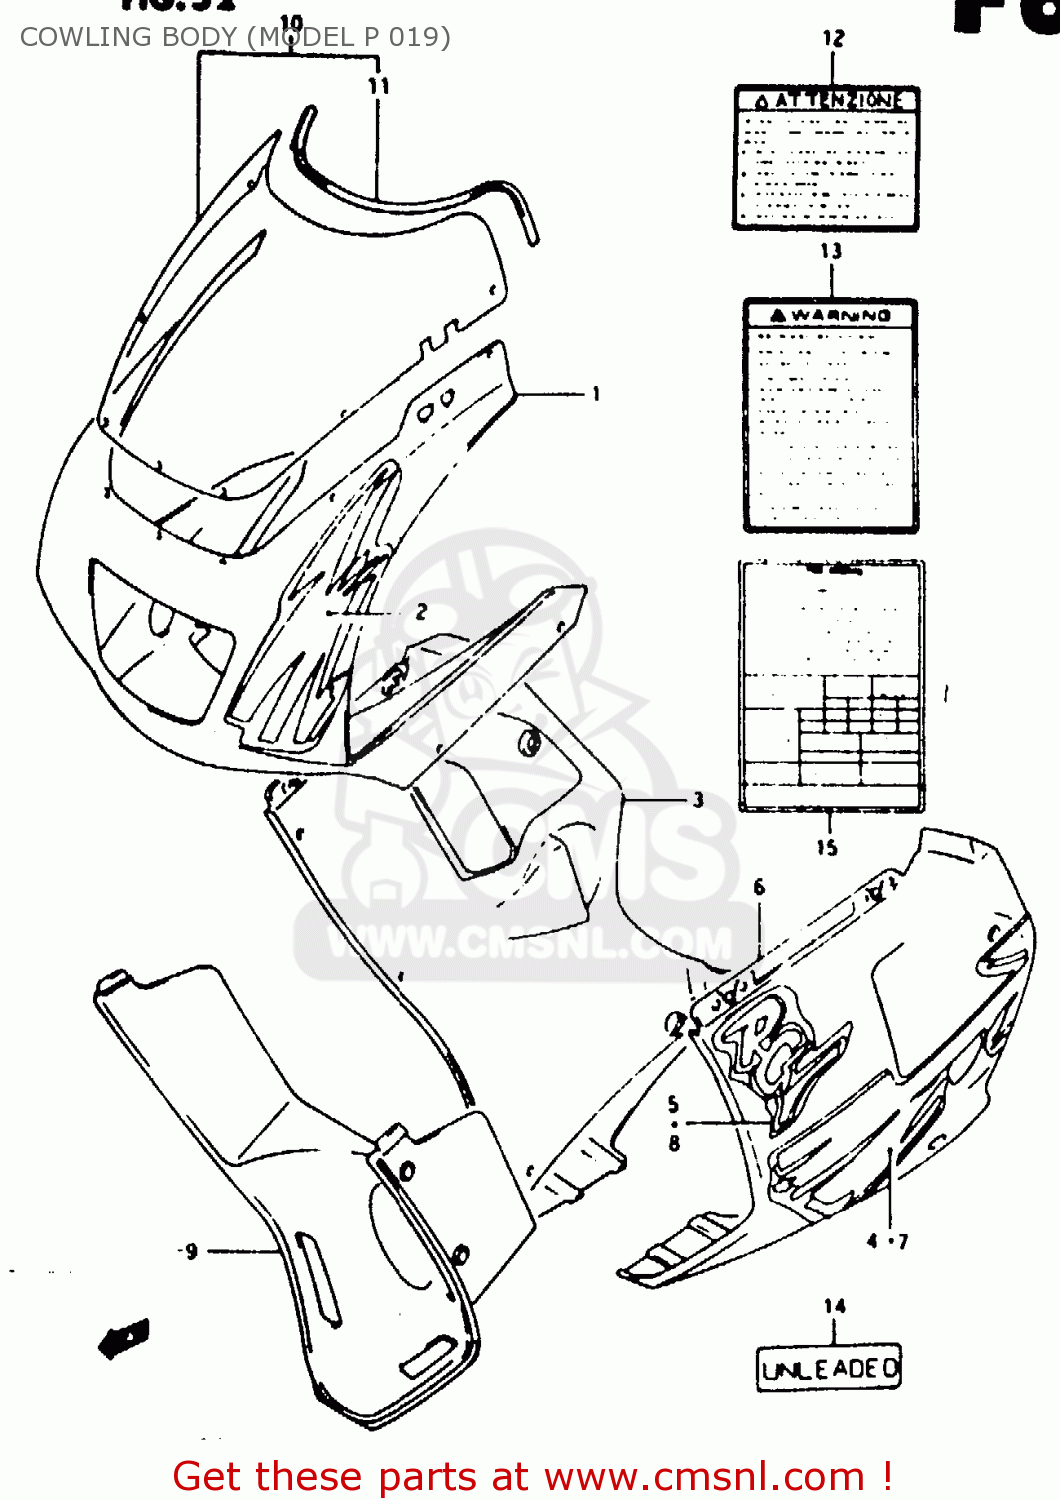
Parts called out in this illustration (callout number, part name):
1	COWLING ASSY, BODY (BLACK)
2	TAPE SET, COWLING
3	COWLING ASSY, UNDER RH (BLACK)
4	TAPE, UNDER RH
5	EMBLEM, UNDER RH
6	COWLING ASSY, UNDER LH (BLACK)
7	TAPE, UNDER LH
8	EMBLEM,COWLING UNDER,L
9	COWLING, UNDER CENTER (BLACK)
10	SCREEN SET, WIND
11	MOLDING
12	LABEL, WARNING SAFETY
13	LABEL (WARNING SCREEN)
14	LABEL,CAUTION
15	LABEL, TIRE AIR PRESSURE
